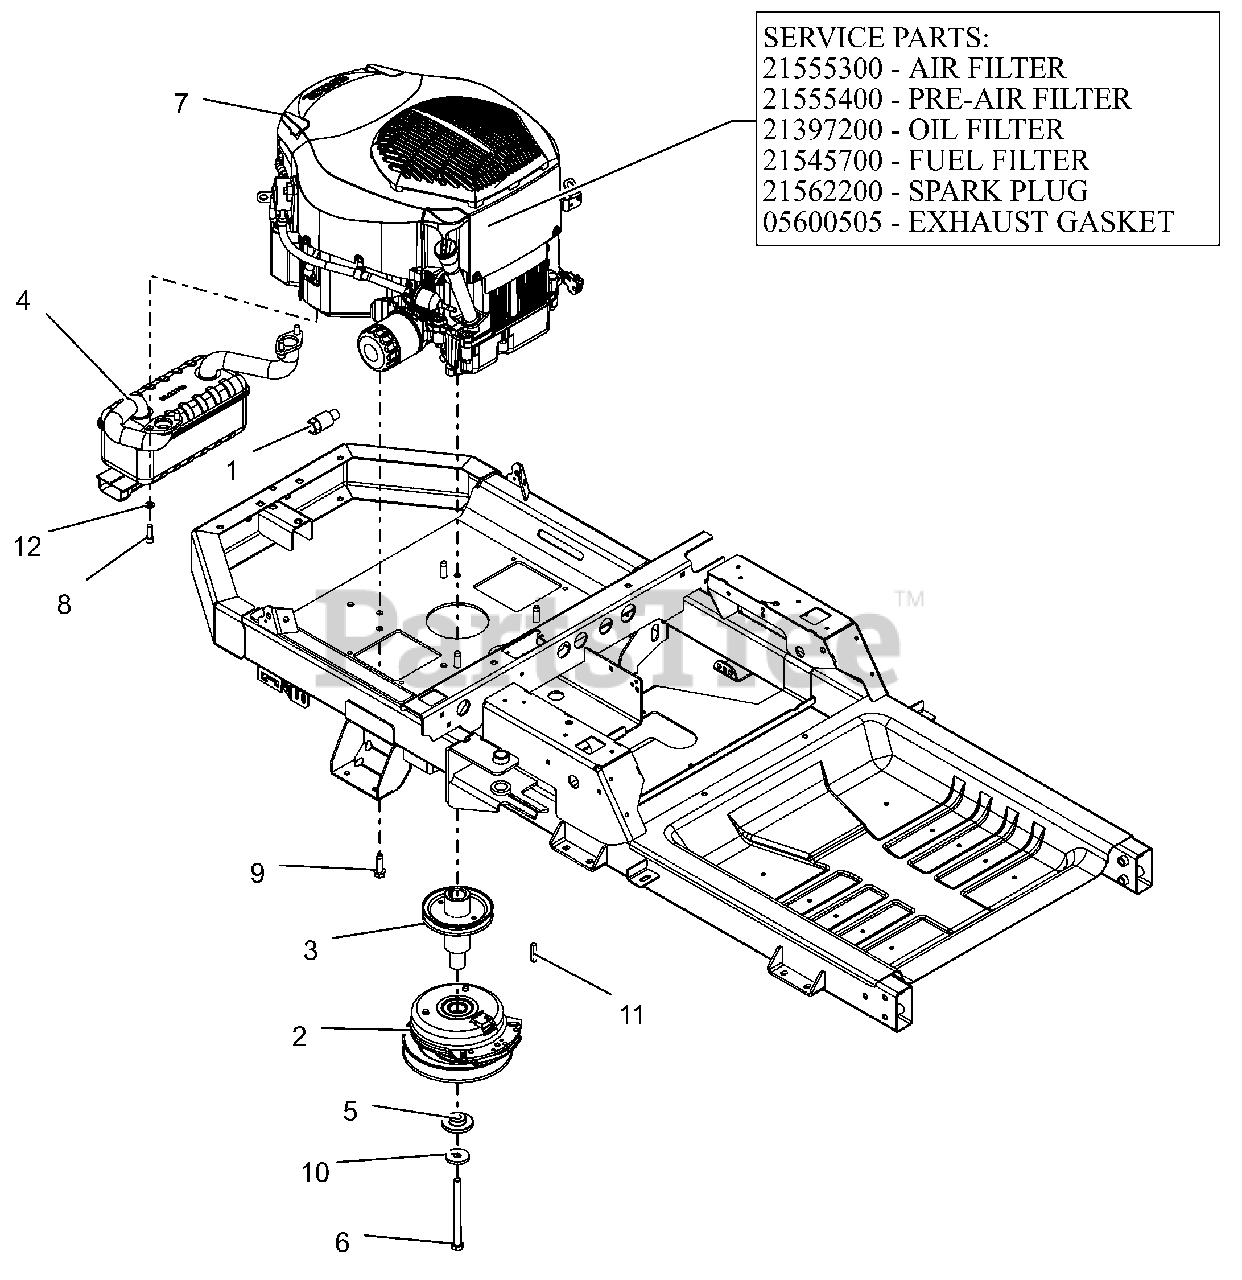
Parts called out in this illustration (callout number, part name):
1	DRAIN, OIL
2	CLUTCH,105FTLB MONOPOLE 6.83"
3	WLDMT, DRIVE SHEAVE (LG XL)CZC
4	MUFFLER, KOHLER
5	BSHG-FLG .469X1.06X.574X2.0
6	BLT-HEX.438-20X5 GR8 YZ NYTORQ
7	ENGINE-KOHLER PRO 24HP W/SC
7	AIR FILTER, KOHLER
7	PRE CLEANER, KOHLER
7	FILTER, OIL - KOH CV20
7	FILTER-FUEL KOHLER COURAGE PRO
7	PLUG, SPARK (RFI)
7	GASKET, MUFFLER KOHLER TWIN
8	SCR, SKH .312-18X.875 GR8 ZCC
9	SCR,TAP .375-16X1.25HWH TR ZCC
10	WASHER, 7/16" SPRING DISK
11	KEY-SQ .25 X 1.25 X .25 SAE
12	WSHR,LK-REG .312X.078 ZCC
